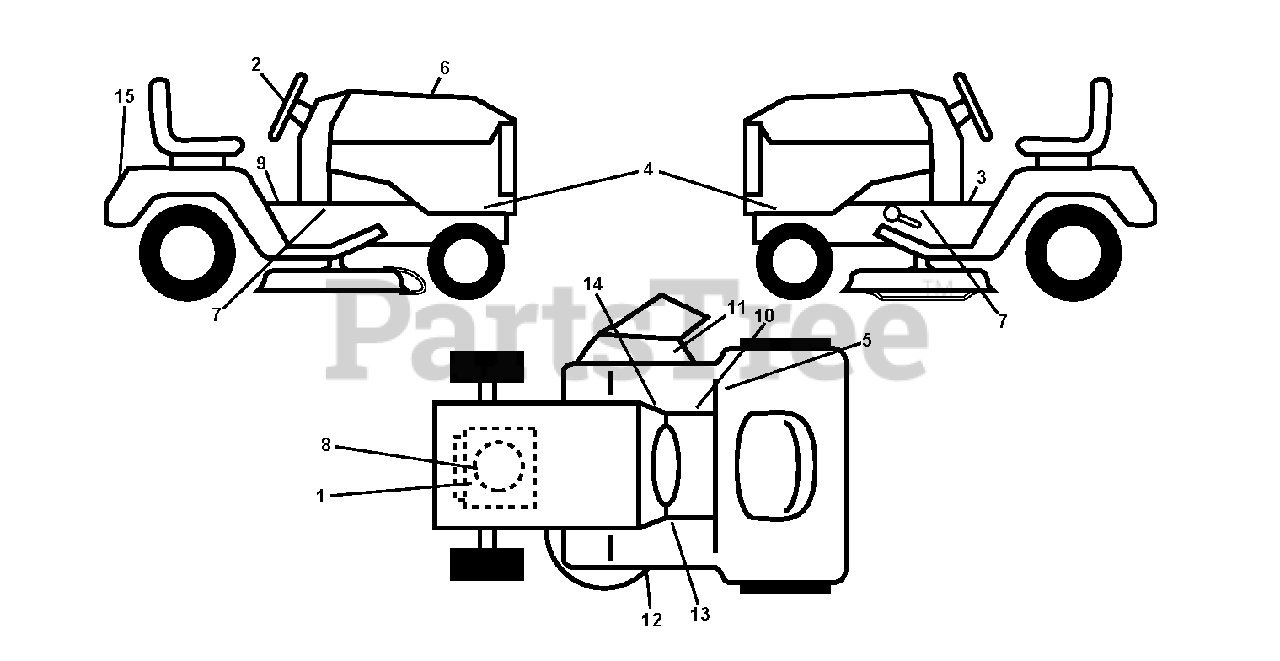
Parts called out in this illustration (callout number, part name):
9	DECAL BTRY SYMBOLS
11	DECAL.WARN.DFLECT/CTFINGR.SRD
14	DECAL PARK BRAKE
